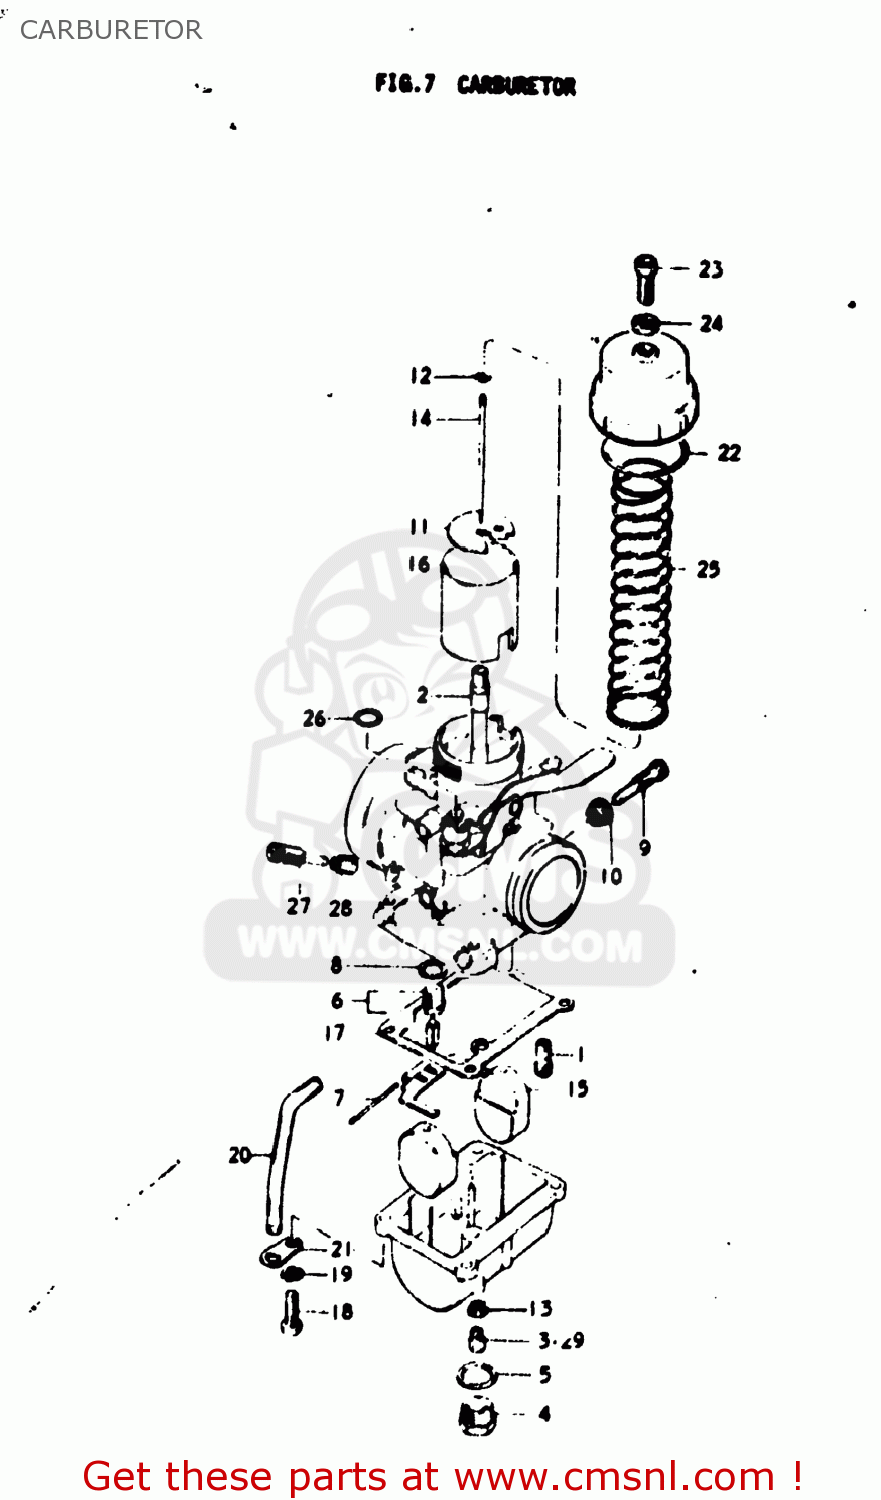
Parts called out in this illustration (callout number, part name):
1	JET
2	JET,NEEDLE
3	JET
4	PLUG
5	GASKET,DRAIN PLUG (MCA)
6	VALVE ASSEMBLY,NEEDLE
7	PIN,FLOAT
8	GASKET,VALVE SEAT (NAS)
9	ADJUSTER
10	NUT, STOP SCREW
11	PLATE,THROTTLE VALVE
12	CLIP
13	RING
14	NEEDLE JET
15	FLOAT
16	VALVE,THROTTLE
17	GASKET,FLOAT CHAMBER
18	SCREW
19	LOCK WASHER
20	HOSE
21	PLATE
22	O-RING
23	ADJUSTER,CABLE
24	NUT,CABLE ADJUSTER LOCK
25	SPRING
26	O RING
27	SCREW,PILOT AIR
28	SPRING
29	JET
